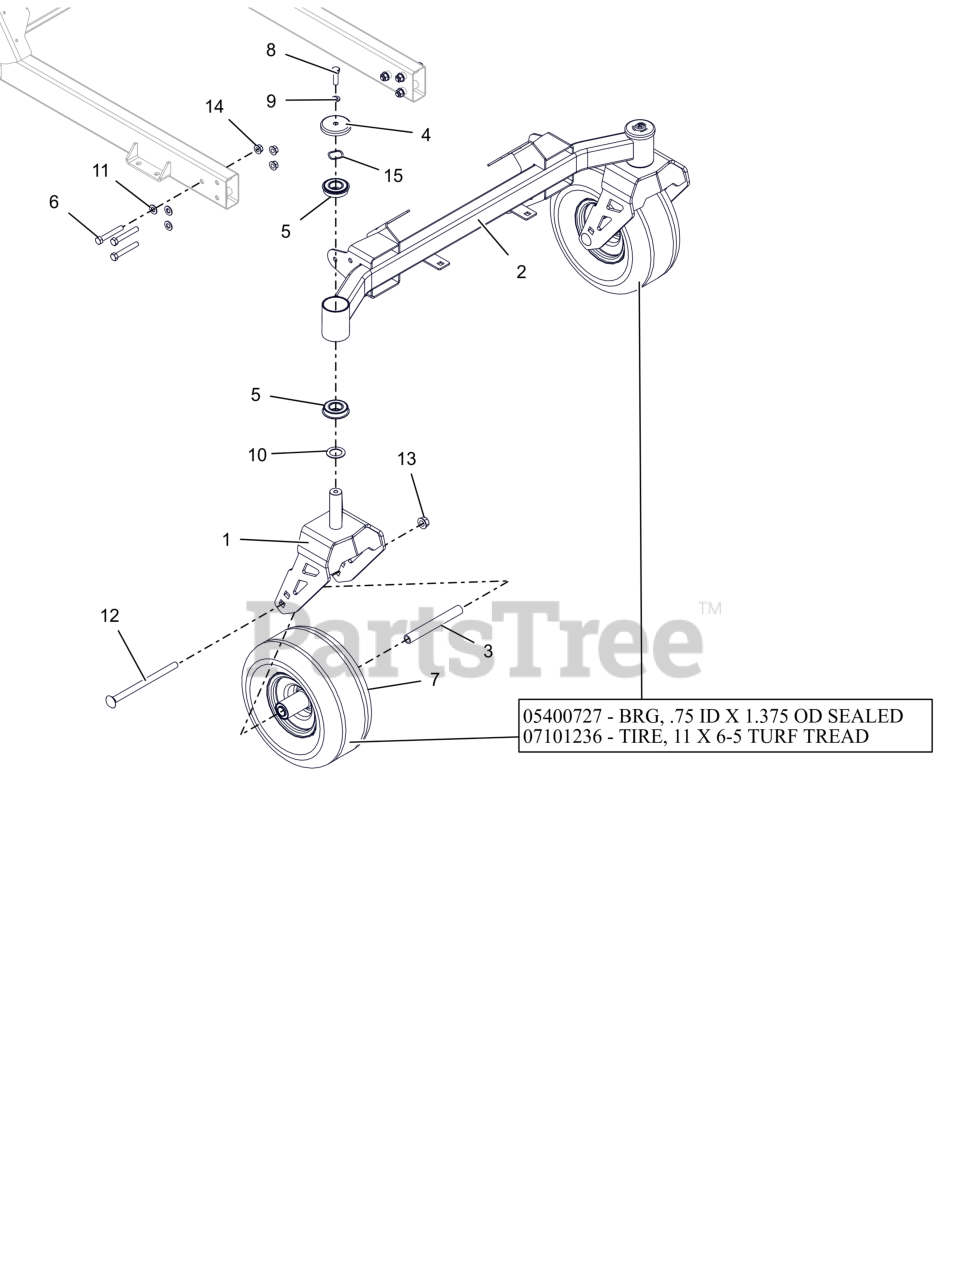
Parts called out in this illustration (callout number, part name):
1	WLDMT, CASTER FORK-XL (RED)
2	WLDMT, FRONT AXLE-X/XL (RED)
3	SPACER, FRONT WHEEL (WIDE 6.0)
4	SHIELD, AXLE BEARING
5	BEARING, BALL -2.000 OD X 1.000 ID X .5625 W/RING
6	BLT, HEX .38-16X2.50 G8 ZCC
7	TIRE/WHEEL ASSY, 11X6-5
7	BRG, .75 ID X 1.375 OD SEALED
7	TIRE, 11X6-5 TURF TREAD
8	BLT, HEX .38-16X1.25 G5 ZCC
9	WSHR,LK-REG .375X.094 ZCC
10	WSHR-HRD-THRS 1.007X1.542X.062
11	WSHR-FL-STL 0.406X0.812X0.055 HRD
12	BLT, RHSN .50-13X7.50 G5 ZCC
13	NUT-LK-TOP-FLG .500-13 GF ZCC
14	NUT-LK-TOP-FLG .375-16 GG ZCC
15	WSHR-WAVE 1.0X1.25X.028 .145FH
